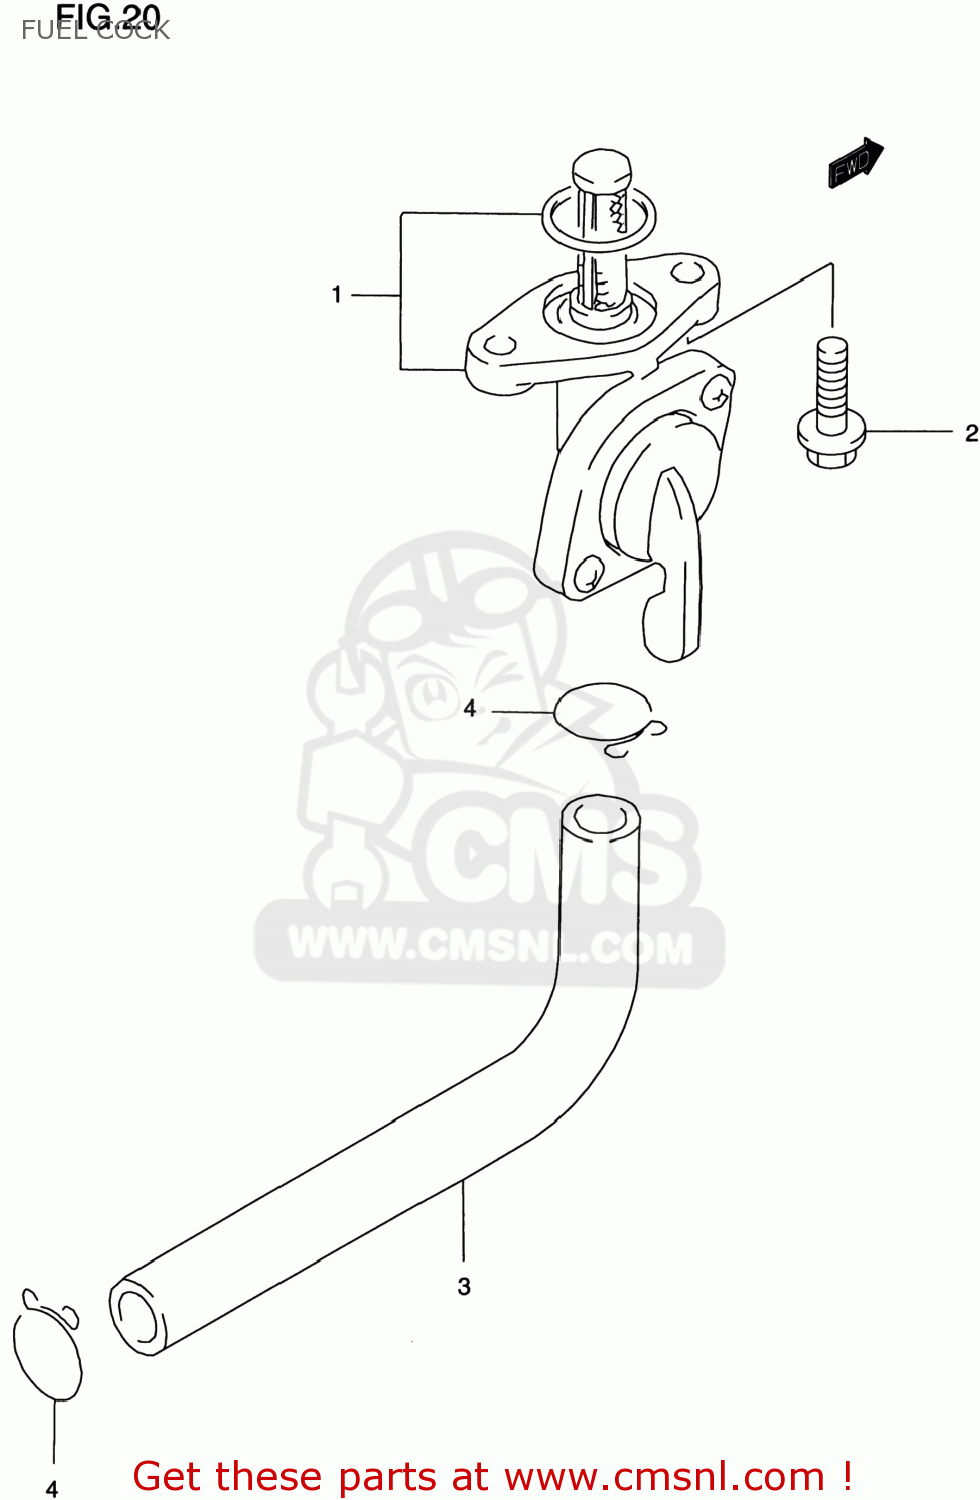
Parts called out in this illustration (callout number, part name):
1	COCK ASSY,FUEL
2	BOLT
3	HOSE(6.5X11.5X600)
4	CLIP
